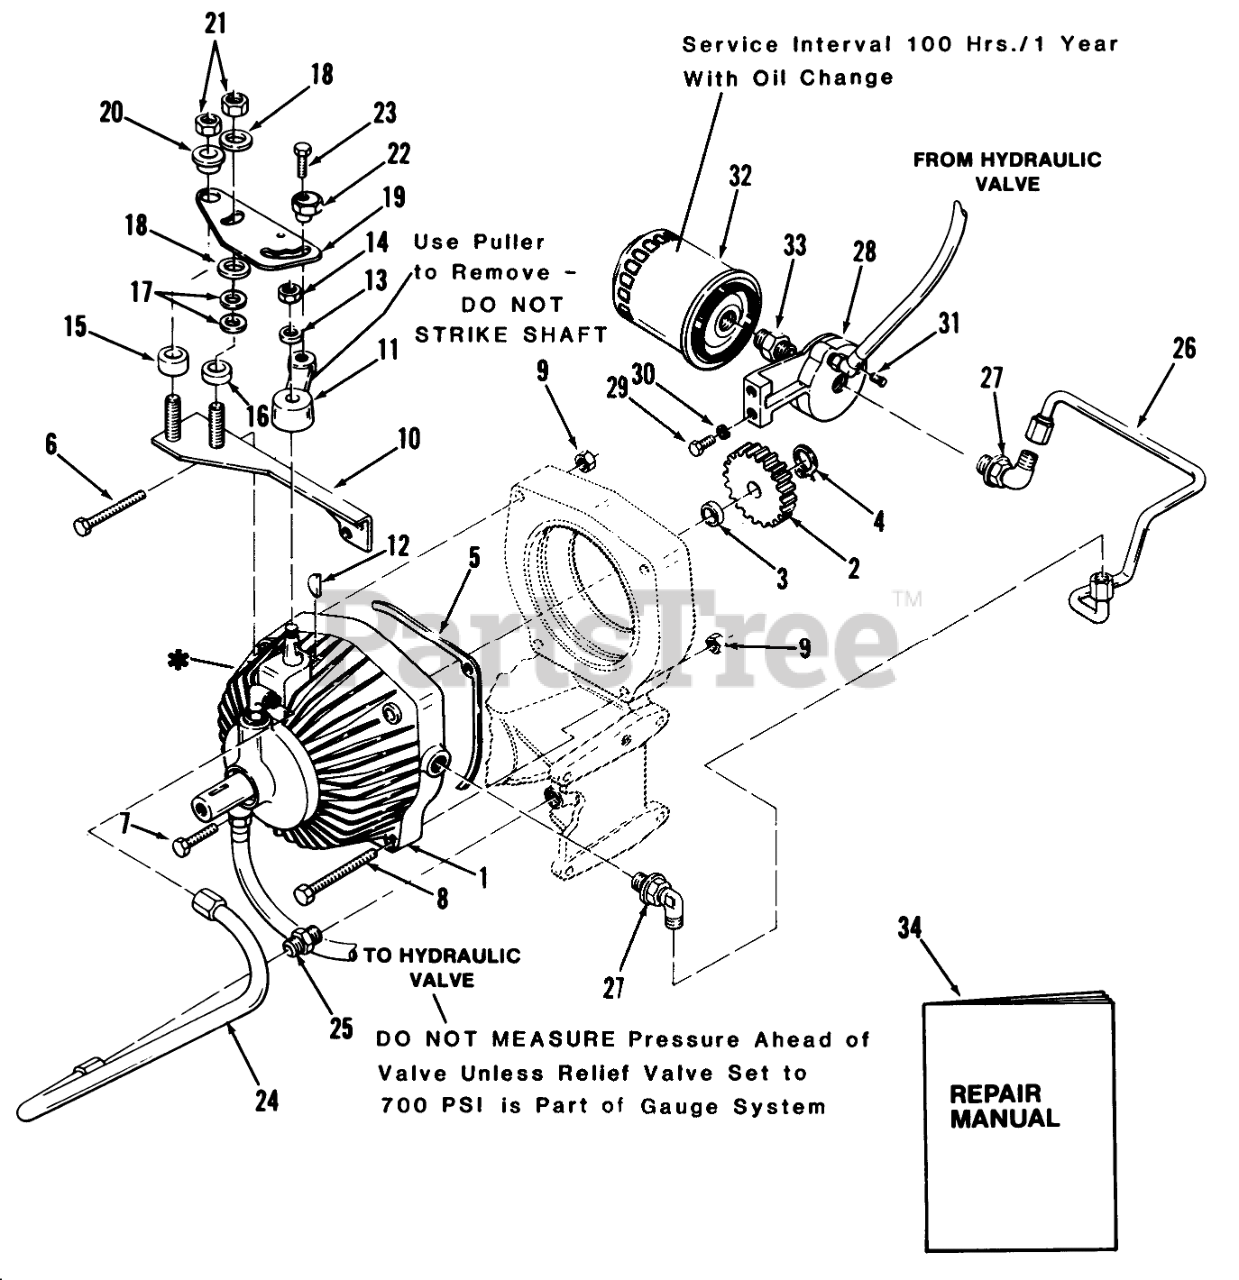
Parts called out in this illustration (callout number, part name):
1	Pump & Motor
2	GEAR 20 TEETH DRIVE
3	SPACER GEAR
4	SNAP RING- 5/8 EXT
5	GASKET
6	Hex Bolt
7	Bolt
8	Bolt 3/8-16 x 6 1/2
9	NUT-LOCK, NI
10	ASSY-PLATE B
11	ARM-SPEED CONTROLB
12	Key #5 Woodruff
13	Washer
14	Nut
15	SPACER-PIVOT
16	SPACER-FRICTION
17	WASHER-SPRING DISC
18	FRICTION WASHER
19	CAM-SPEED CONTROL (NS)
20	CAM-SPACER
23	Bolt
24	ASSY-TUBE SUCTION
25	FITTING-TUBE
26	ASM-TUBE FILTER OUTL
27	ELBOW
28	BASE-FILTER
29	SCREW-HH
30	WASHER-LOCK
31	PLUG 1/4 PIPE ALLEN
32	Filter-Oil
33	FITTING
34	Repair Manual
